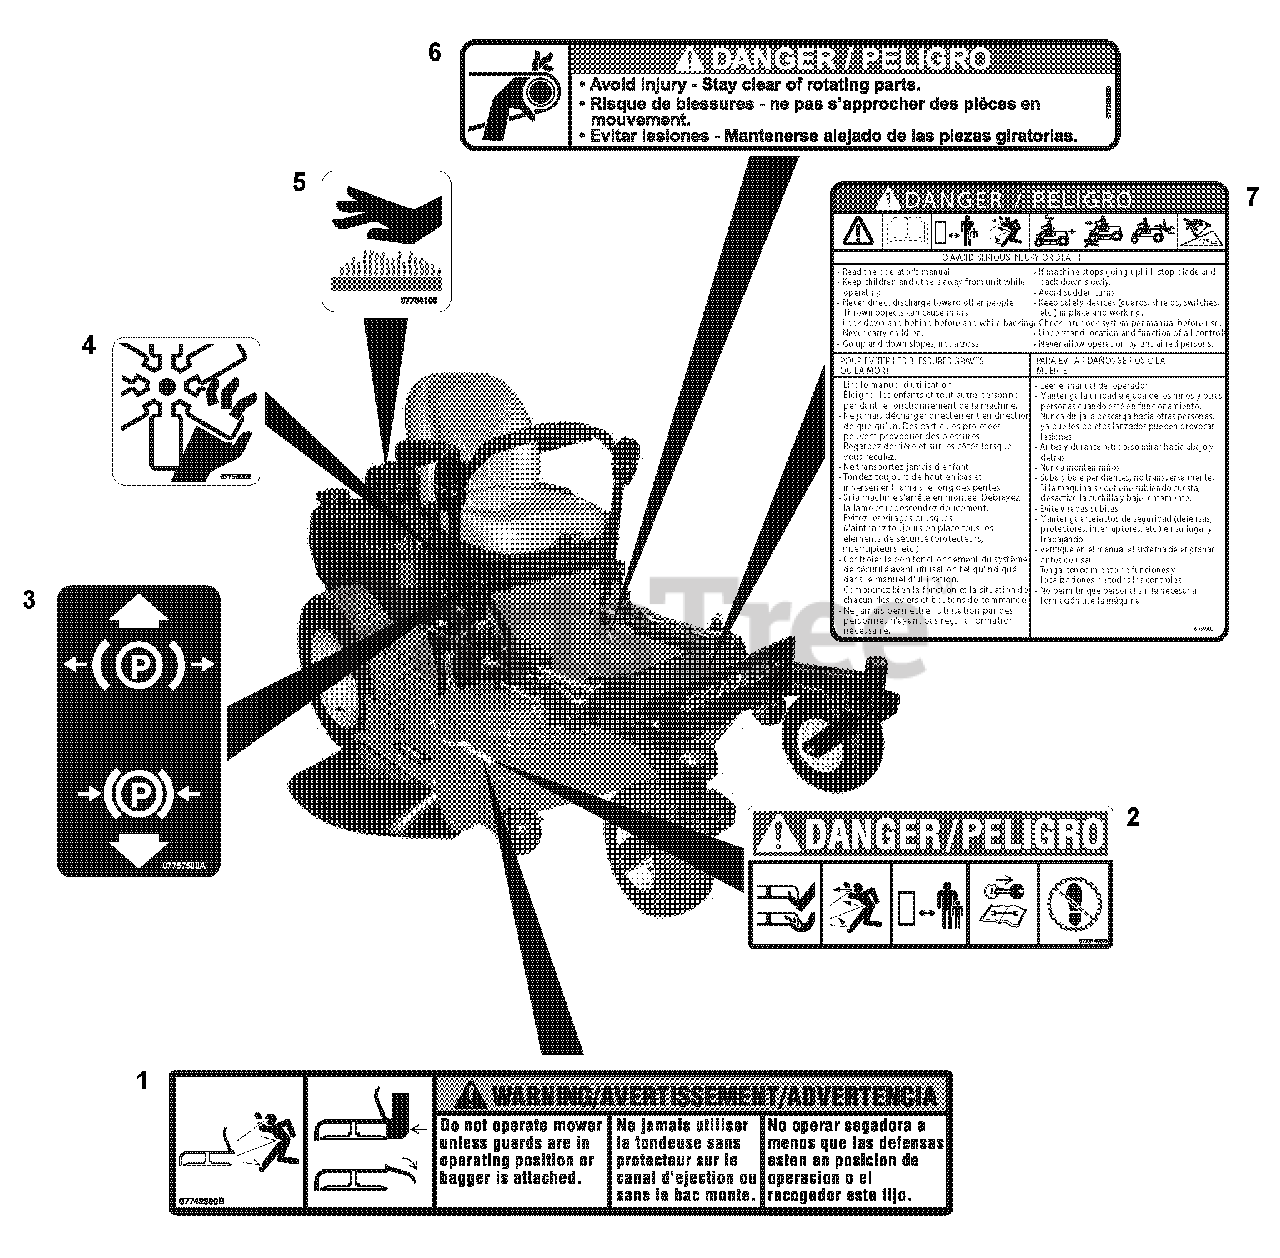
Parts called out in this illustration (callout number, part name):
1	DECAL, WARNING
2	DECAL, MOWER PAN DANGER
3	DECAL, PARKING BRAKE LEVER
4	DECAL, DANGER FAN
5	DECAL, HOT SURFACE
6	DECAL- DANGER
7	DECAL, DANGER - BILINGUAL
